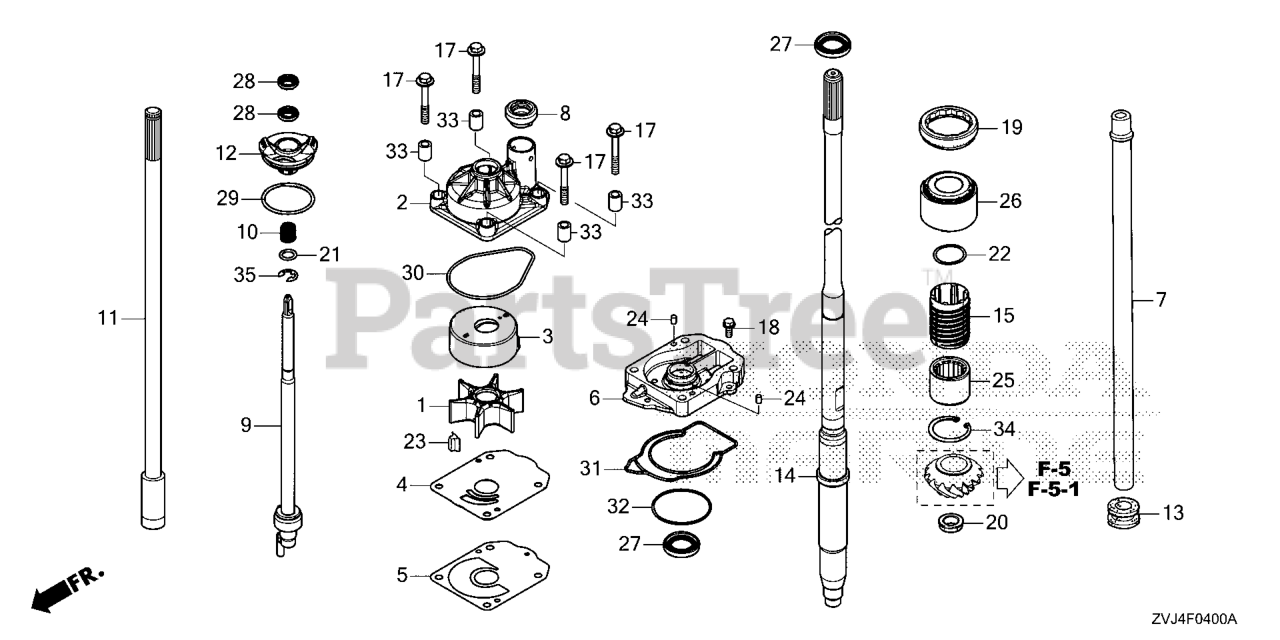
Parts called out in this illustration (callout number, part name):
1	IMPELLER, PUMP
2	HOUSING, IMPELLER
3	LINER, PUMP
4	COVER, IMPELLER
5	GASKET B, IMPELLER
6	HOUSING, WATER PUMP
6	HSG, WATER PUMP
7	TUBE, WATER (XXL)
8	RING, WATER TUBE SEAL
9	ROD, SHIFT (COUNTER ROTATION)
10	SPRING, SHIFT ROD
11	ROD A, SHIFT (XXL)
12	HOLDER, SHIFT ROD
13	GROMMET, EXTENSION CASE
14	SHAFT, VERTICAL (XXL)
15	SLINGER, OIL
16	GEAR, PINION (COUNTER ROTATION)
17	BOLT-WASHER (8X60)
18	BOLT, FLANGE (6X16) (SUS)
19	NUT, LOCK (68MM)
20	NUT, HEX. (18MM)
21	WASHER, PLAIN (12MM)
22	SHIM A, GEAR (0.10)
22	SHIM B, GEAR (0.15)
22	SHIM C, GEAR (0.30)
22	SHIM D, GEAR (0.50)
23	KEY, WOODRUFF
24	PIN, DOWEL (6X10)
25	BEARING, NEEDLE (30.5X47X37)
26	BEARING, TAPER ROLLER (32X66X49)
27	SEAL, WATER (26X42X7)
28	SEAL, WATER (12X21X6)
29	O-RING (49.4X3.1)
30	O-RING, WATER PUMP
31	O-RING, WATER PUMP HOUSING
32	O-RING (65.4X2.4)
33	COLLAR, DISTANCE
34	CIRCLIP (INNER) (47MM)
35	E-RING (10MM)
